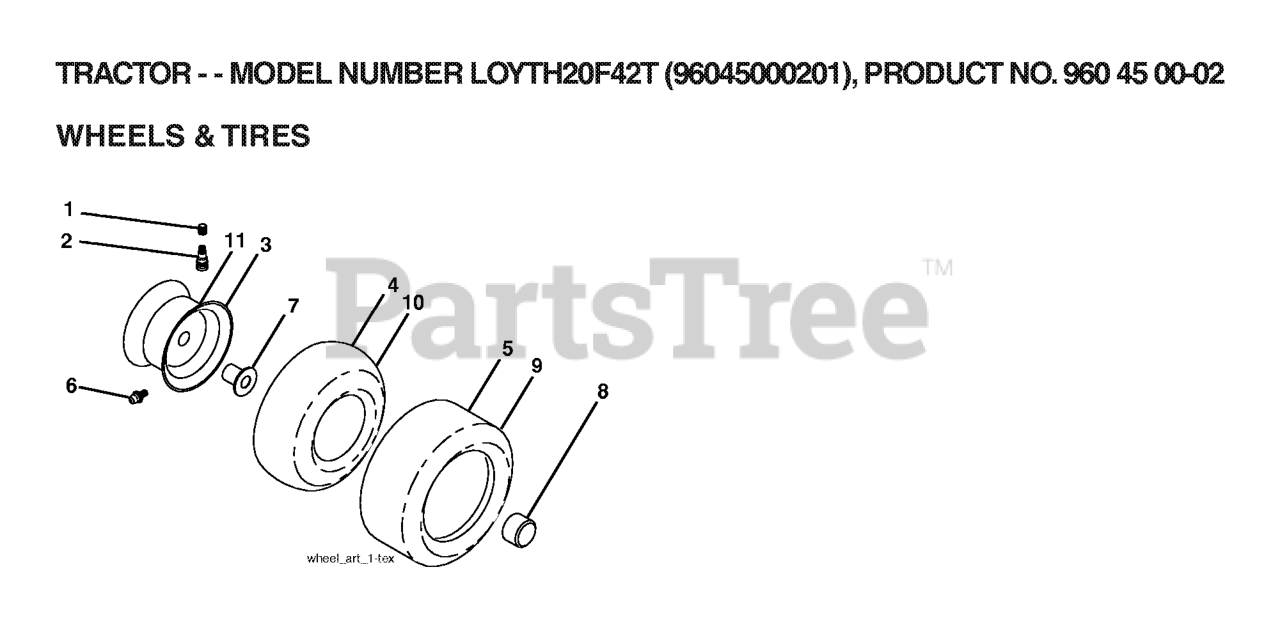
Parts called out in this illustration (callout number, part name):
2	VALVE STEM LT
3	RIM ASM 6" FRONT SILVER
4	TUBE.5.3/4.5/6
5	TIRE HEAVY DUTY
6	FITTING LT
7	BEARING T
8	CAP, AXLE BLK
9	TIRE.20X8-8.TURF.SAVER
10	TUBE
11	RIM ASM 8" REAR SILVER
